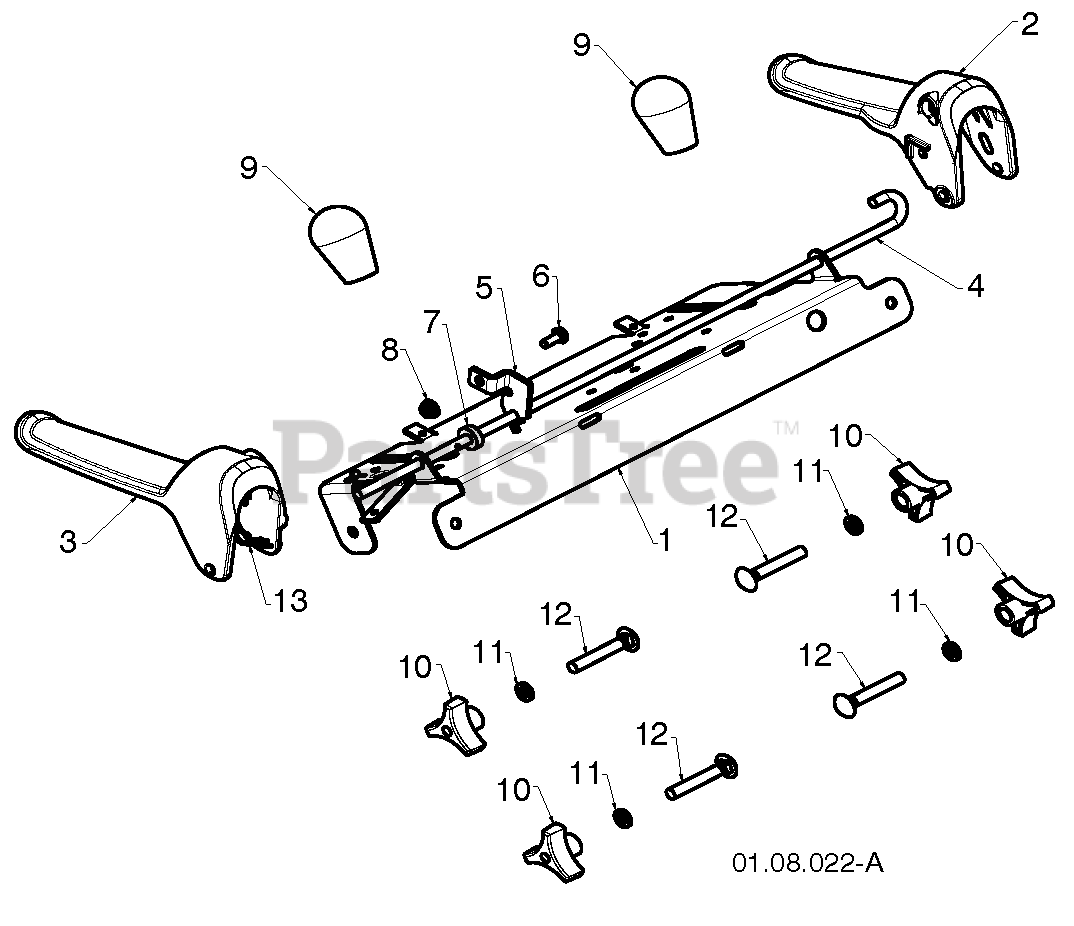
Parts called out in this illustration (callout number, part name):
1	CONTROL PANEL
2	LEVER.CONTROL.LH.PL.BLACK
3	LEVER.CONTROL.RH.PL.BLACK
4	BAIL.CONTROL.INTERLOCK.SNOW
5	BRACKET.ARM.IMPELLER.ROD.YZ
6	BOLT
7	SPACER.CONTROL.LEVER
9	KNOB.OVERMOLD.DS.HUSQVARNA/BLK
10	KNOB.HANDLE.3/8.TRI-POINT.BLAC
11	WASHER
12	BOLT 3/8-16 X 2-1/4
13	SPRING RETAINER
